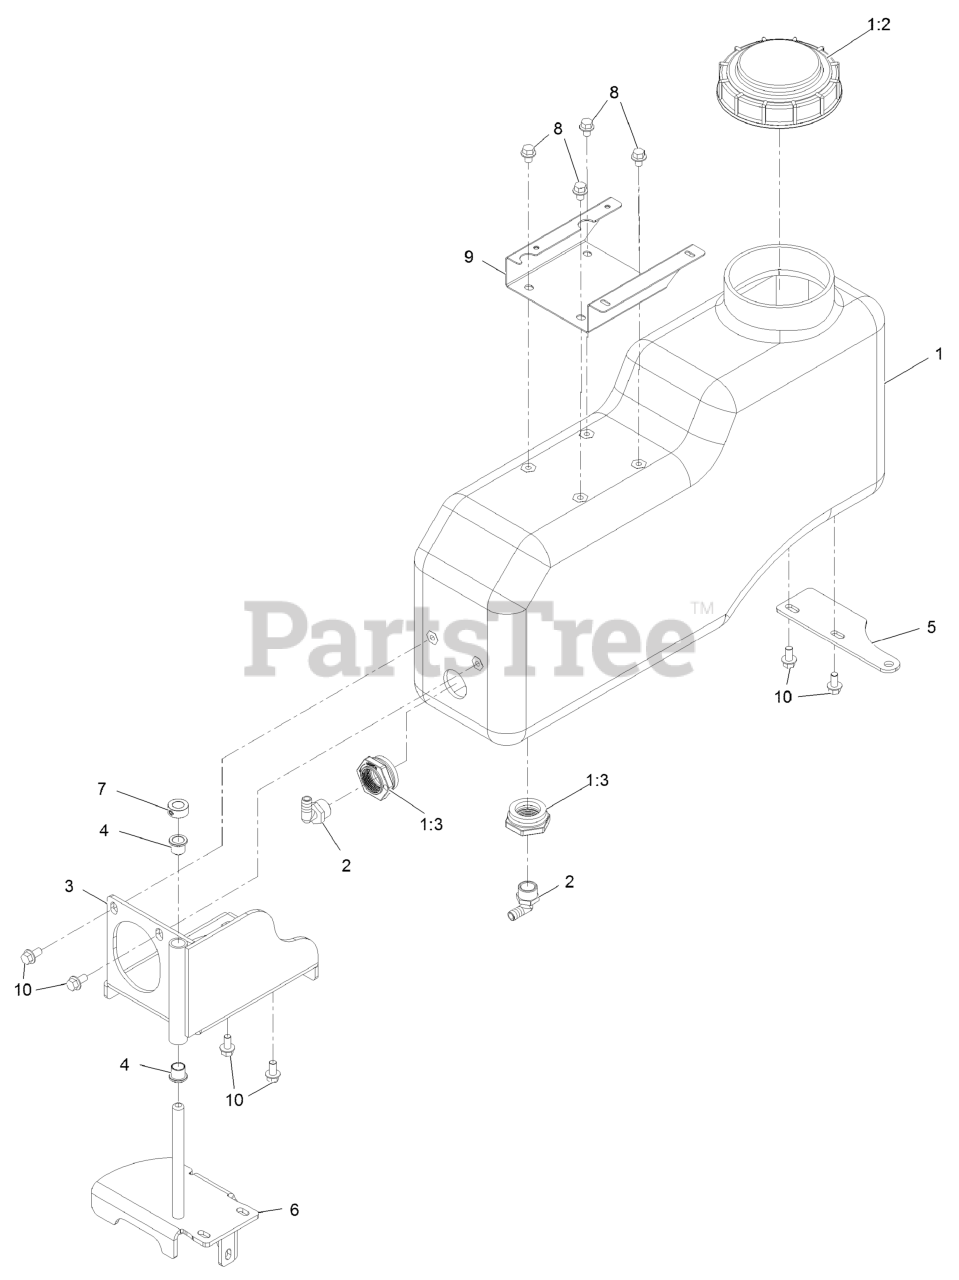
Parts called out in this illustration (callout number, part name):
1	ASM-TANK, RT
1:2	CAP-TANK, SPRAY
1:3	FITTING-BULKHEAD
2	FITTING-ELBOW, 90
3	WLD, WING, TANK, BOTTOM,
4	BUSHING-FLANGE
5	PLATE, PIVOT LOCK, TANK, JR36
6	WLD, WING, TANK, BOTTOM,
7	5/8 SHAFT COLLAR
8	Screw-HHF
9	PLATFORM-VALVE, LIQUID
10	SCREW-HHF
